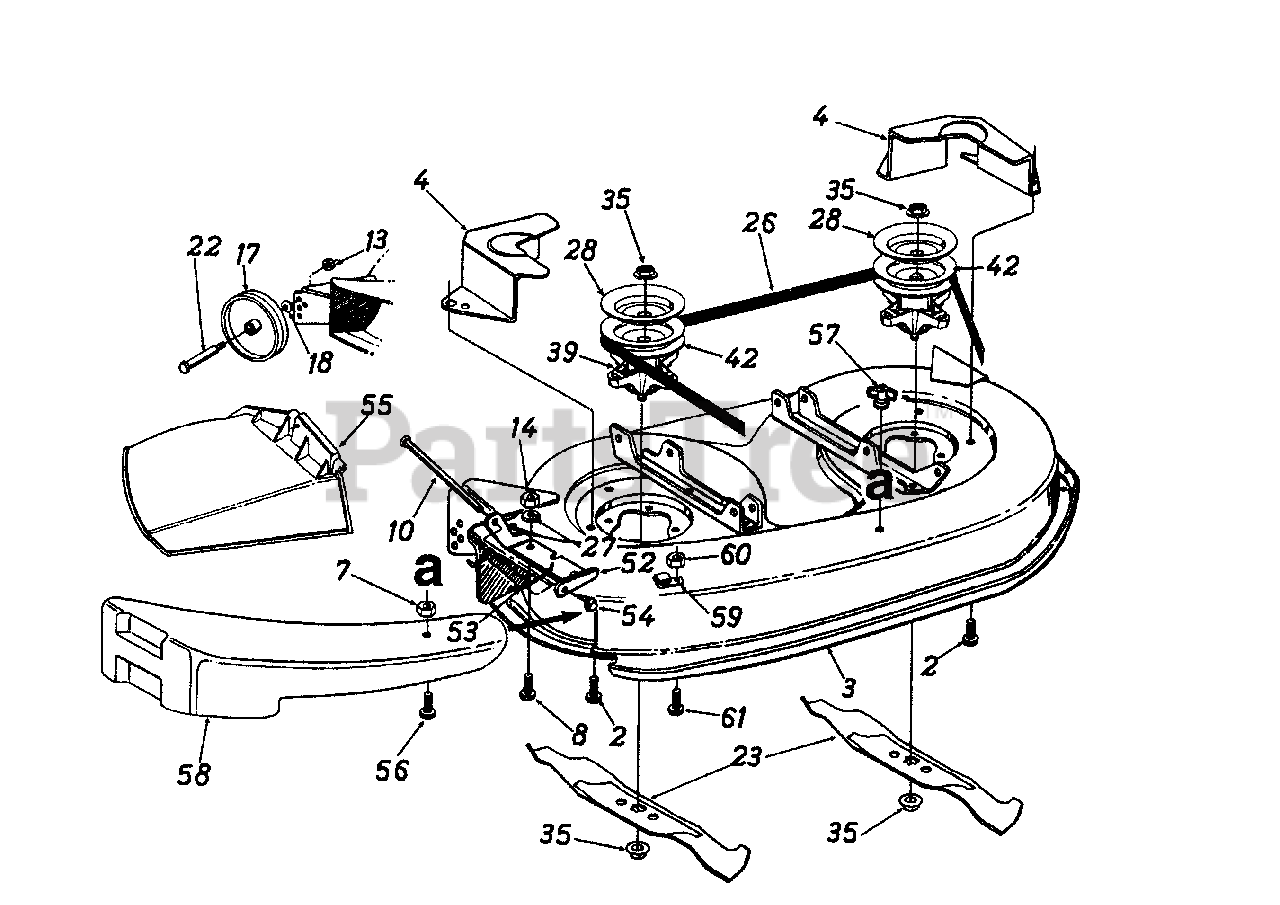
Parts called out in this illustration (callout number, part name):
2	Hex Wash. Hd. TT-Tap Scr. 5/16-18 x .75" Lg.
7	Hex L-Nut 1/4-20 Thd.
8	Hex Bolt 1/4-20 x .62"
10	Hinge Pin
13	Hex Top L-Nut 3/8-16 Thd.
14	Hex Nut 1/4-20 Thd. (Gr. 5)
17	Deck Wheel--5"
18	Bell-Wash. .40" I.D. x .88" O.D.
22	Shld. Bolt .498" Dia. x 1.53"
23	3 in 1 Blade
26	V-Belt
27	Bell-Wash. 1/4" I.D.
28	Brake Disc
35	Hex Flange Nut 5/8-18 Thd.
39	Blade Spindle Ass'y. Comp.
42	5" Dia. Pulley
52	Hinge Mtg. Brkt.
53	Torsion Spring
54	Push Nut
55	Chute Ass'y. Comp.
56	Hex Bolt 1/4-20 x 1" Lg.
57	Wing Nut 1/4-20 Thd.
58	Mulching Plug
59	Retainer Hook Brkt.
60	Hex Sems Nut 1/4-20 Thd.
61	Hex Bolt 1/4-20 x .62" Lg.
